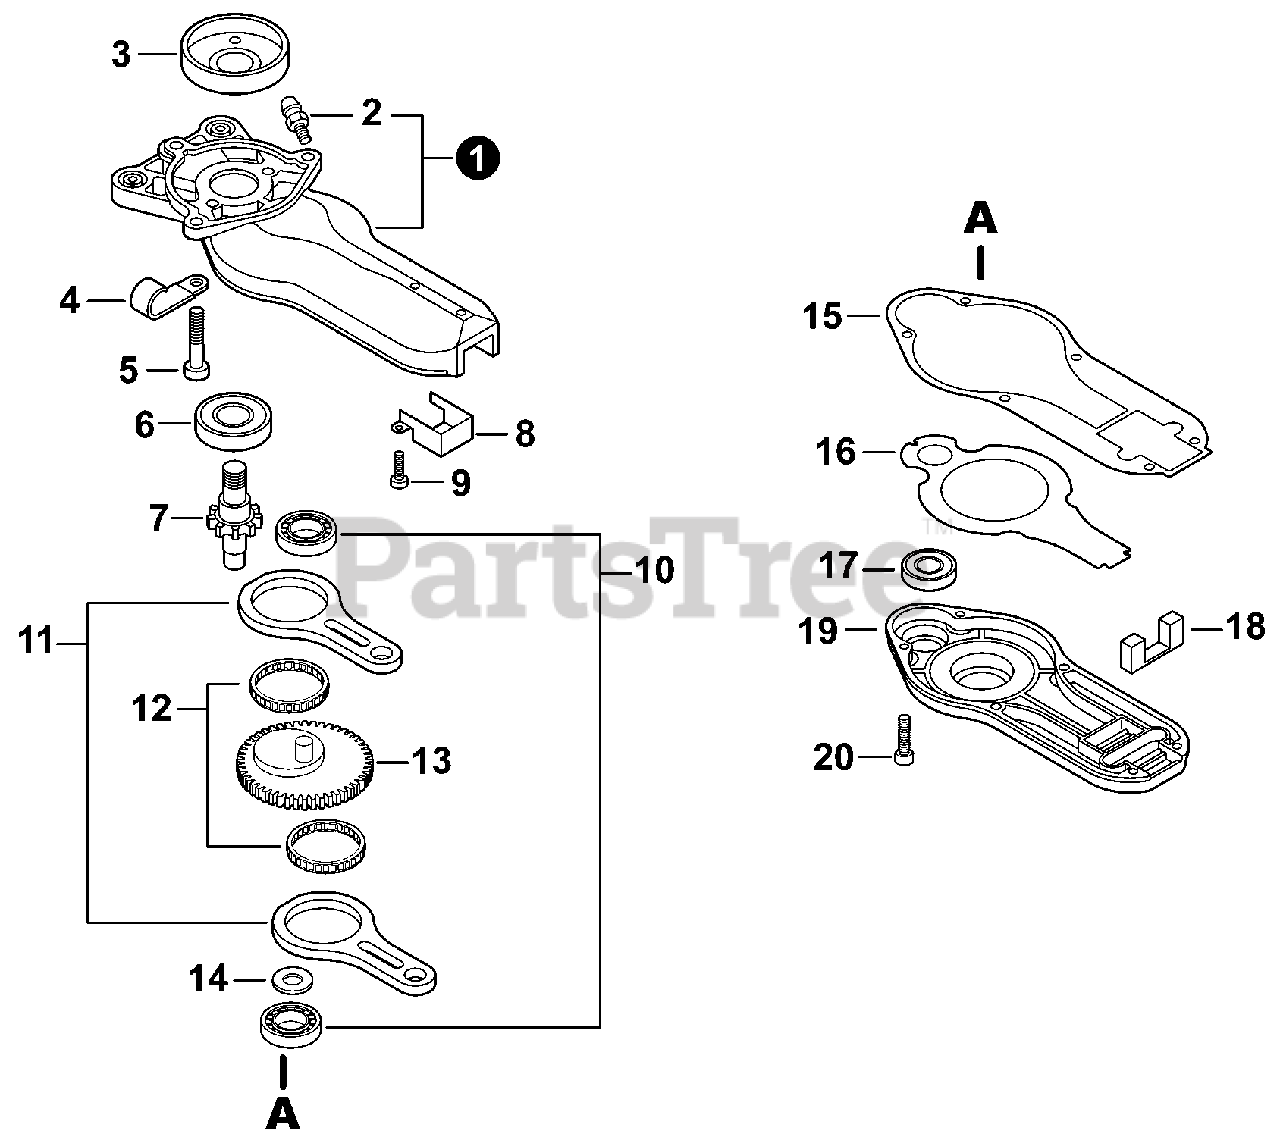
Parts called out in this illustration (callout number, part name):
1	GEAR CASE ASSY
2	FITTING, GREASE
3	DRUM, CLUTCH
5	BOLT, TORX 6×40
6	BEARING, BALL 6200
7	GEAR, SPUR
8	GUIDE, BLADE
9	BOLT, TORX 4×10
10	BEARING, BALL 6200
11	ROD, CONNECTING
12	BEARING, NEEDLE 30
13	GEAR, SPUR
14	WASHER 10
15	GASKET, GEAR CASE
16	PLATE, GEAR CASE
17	BEARING, BALL 608ZZ
19	COVER, GEAR CASE
20	BOLT, TORX 4×16
